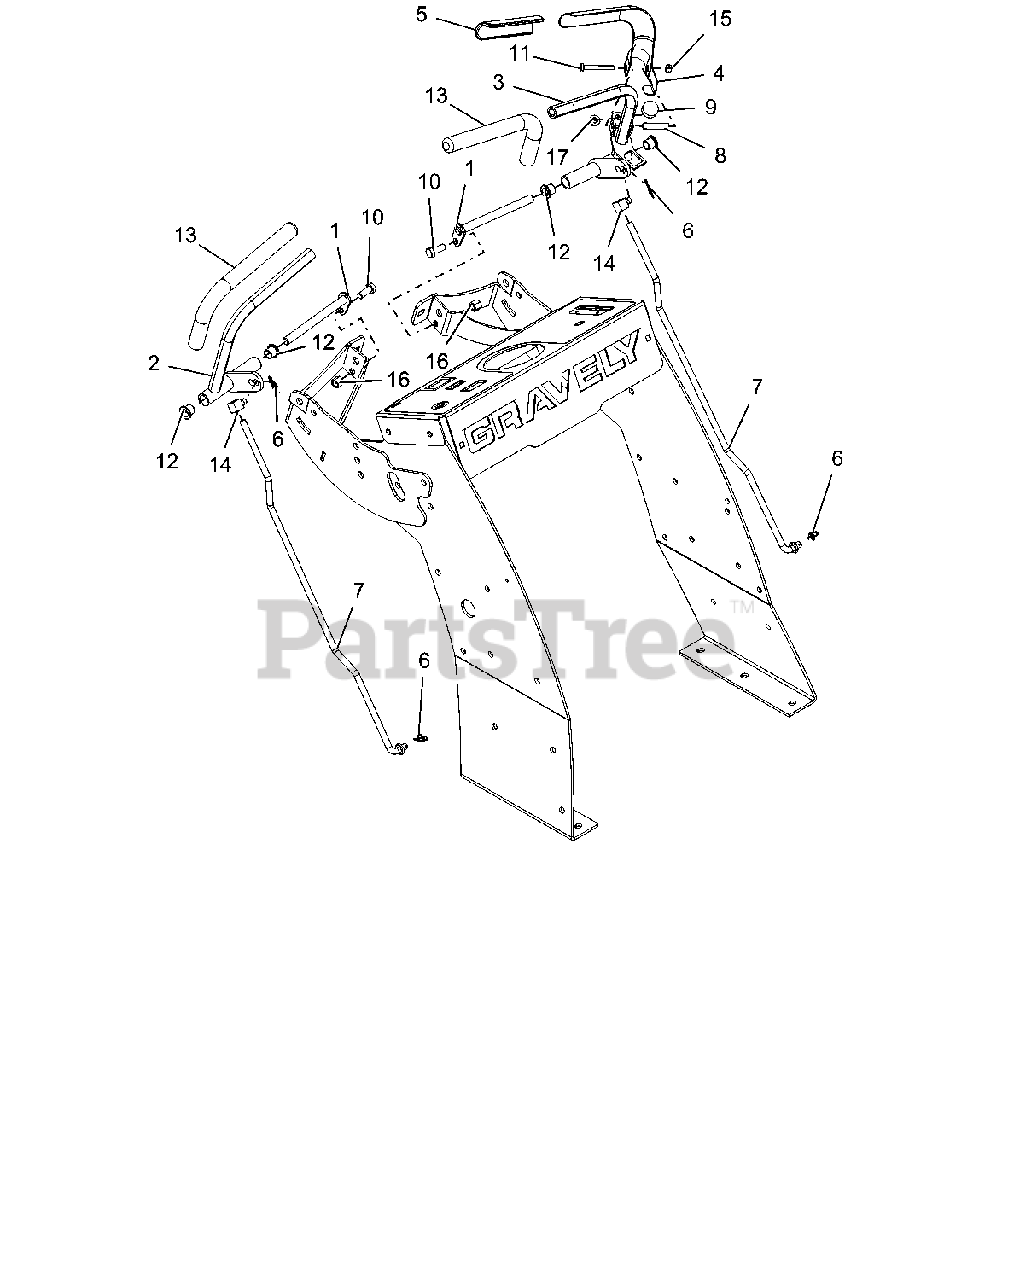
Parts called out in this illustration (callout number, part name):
1	WLDMT, PIN & LOCK
2	WLDT, RH DRIVE LEVER 5 DEG-BLACK
3	WLDT, LH DRIVE LEVER-BLACK
4	WMT, OPC HANDLE-BLACK
5	GRIP, CLUTCH LEVER, LH AND RH
6	RING, RUE .375 x .054 x 1.254
7	ROD, DRIVE TWIN LOOP DBL OFST
8	BSHG, OPERATOR PRESENCE
9	BUMPER, RUBBER
10	BLT-HEX .38-16X1.00 GR5 YWZC
11	BLT-HEX .25-20X2.00 GR5 YWZC
12	BRG, FLG .500 X .625 X .500 BRNZ
13	GRIP, CONTROL
14	SWIVEL, 3/8-24
15	NUT-LK-CTR .25-20 YWZC
16	NUT-LK-NYL .38-16 YWZC
17	@NUT-SPNLK-FLG .312-18 YWZC
